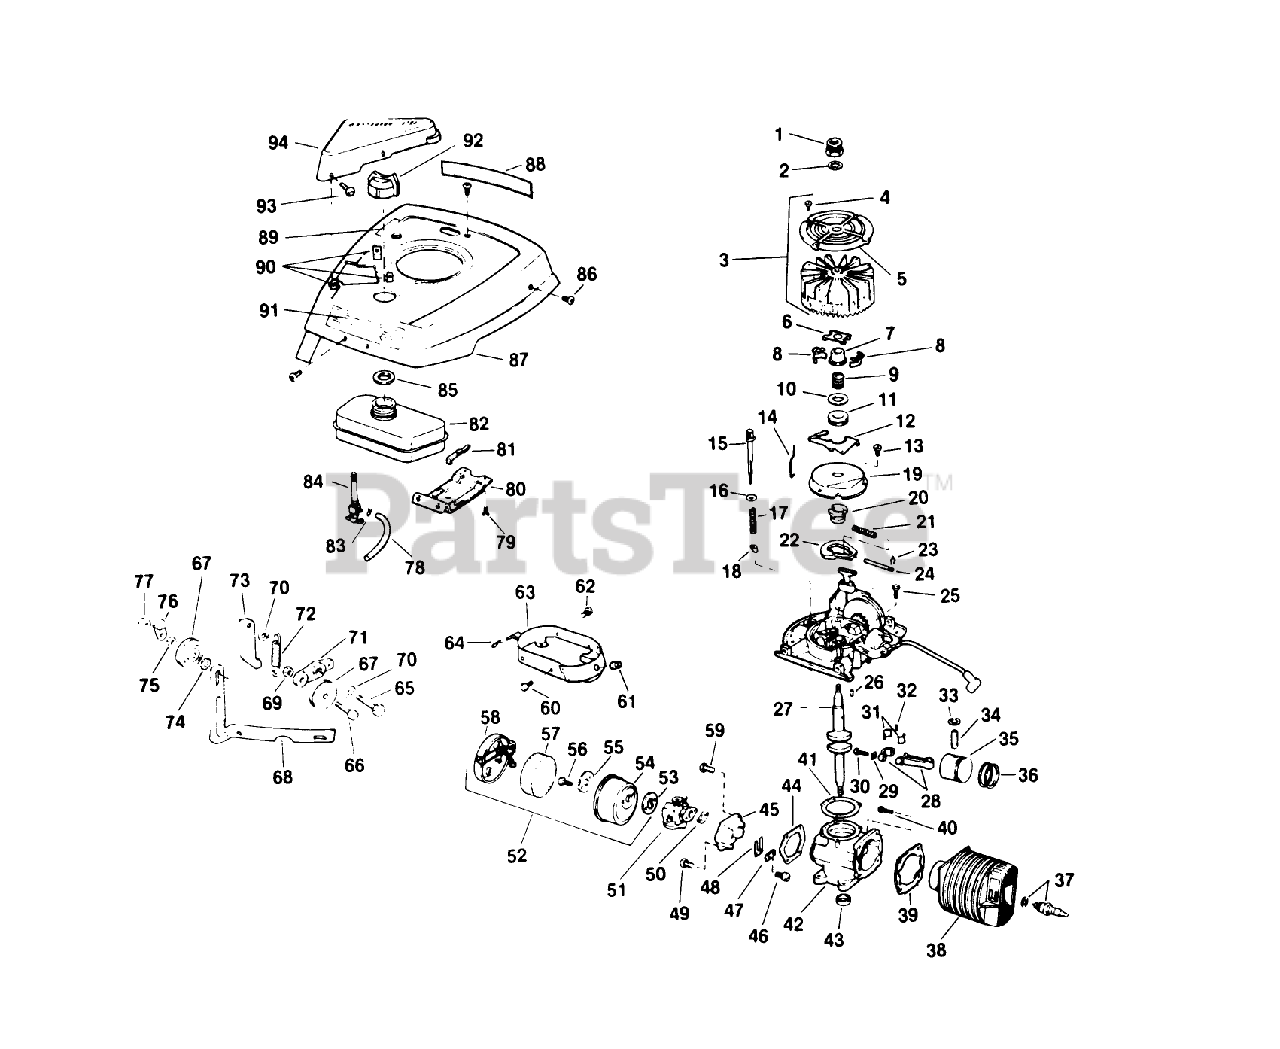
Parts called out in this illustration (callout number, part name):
1	PULLEY
3	Flywheel Screen Assy.
4	SCREW F
6	YOKE S
7	COLLAR S
11	THRUST COLLAR S
12	LEVER-GOVERNOR S
13	SCREW S
14	ROD S
17	SPRING S
19	DUST COVER S
20	SPARK ADV. S
21	SPARK ADV. SPRING S
22	FLYWEIGHT S
23	SPARK ADJ. SPRING
24	PIN,SPARK ADV. S
26	KEY
30	SCREW
31	LINER ASM
33	RING-RETAINING
37	Spark Plug and Gasket
39	GASKET S
41	GASKET S
44	GASKET S
45	REED PLATE AY. S
47	PLATE-BACKUP, REED
49	SCREW S
50	GASKET S
53	GASKET S
56	SCREW S
57	AIR FIL.ELEM S
59	SCREW S
60	SCREW S
61	NUT-CLIP
62	Screw
67	IDLER PULLEY
69	LOCKNUT E
77	LOCKNUT E
78	GAS LINE
79	SCREW S
81	SPRING
83	CLAMP - HOSE S
84	VALVE&SCREEN SM
86	SCREW S
91	Decal-Instructions
94	BELT COVER AY
